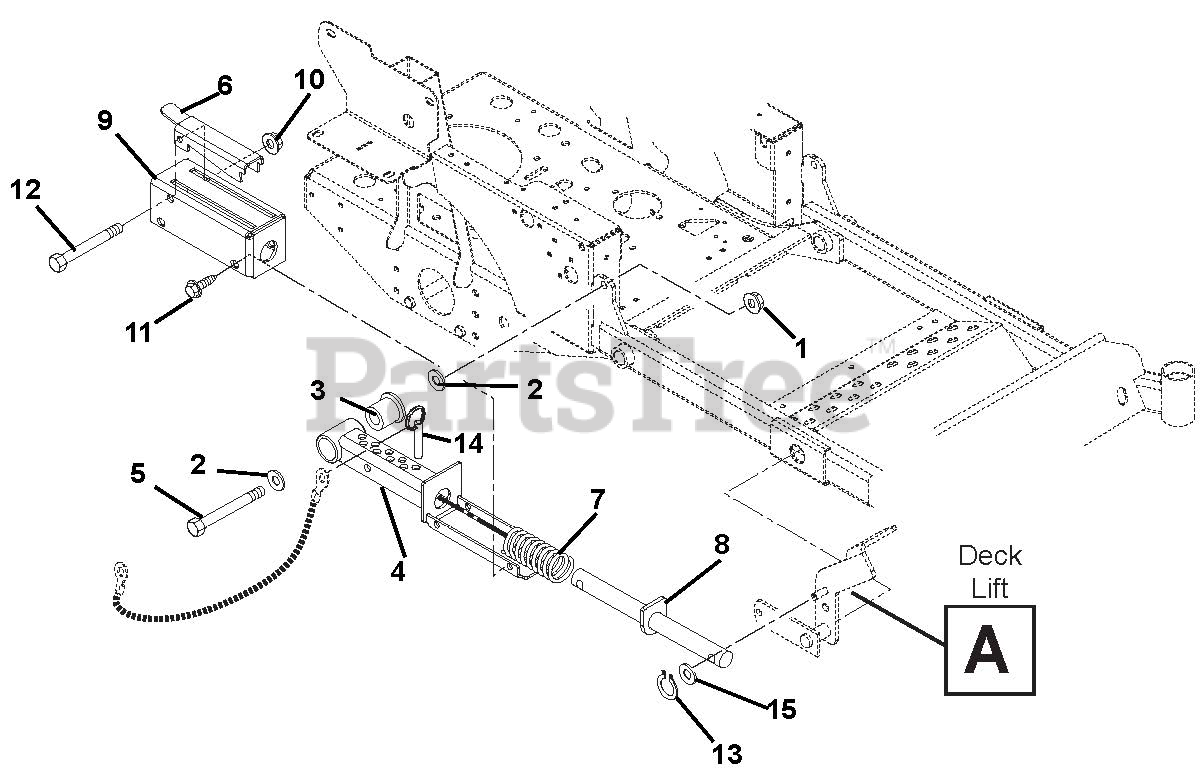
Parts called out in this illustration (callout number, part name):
1	Nut, Locking Top Flange .50-13
2	Washer, Flat Steel .531 x 1.25 x .10
3	Bearing, Pedestal
4	Weldment, Mechanical Lift
5	Bolt, Hex .50-13 x 3.75 Grade 5
6	Lock-Up, Mechanical Lift
7	Spring, Compression 1.13 x 1.48 x 5.10
7	Spring, Compression 1.13 x 1.47 x 5.10
8	Weldment, Mechanical Lift Shaft
9	Weldment, Mechanical Lift Cover
10	Nut, Nyloc Flange 3/8-16
11	Screw, Tapping .38-16 x .50 Hex Washer Head
12	Bolt, Hex .38-16 x 3.25 Grade 5
13	Ring, Retaining External .50 x .05
14	Pin, Spring Ball .375 O.D. x 1.50
15	Washer, Flat Steel .531 x 1.25 x .10
